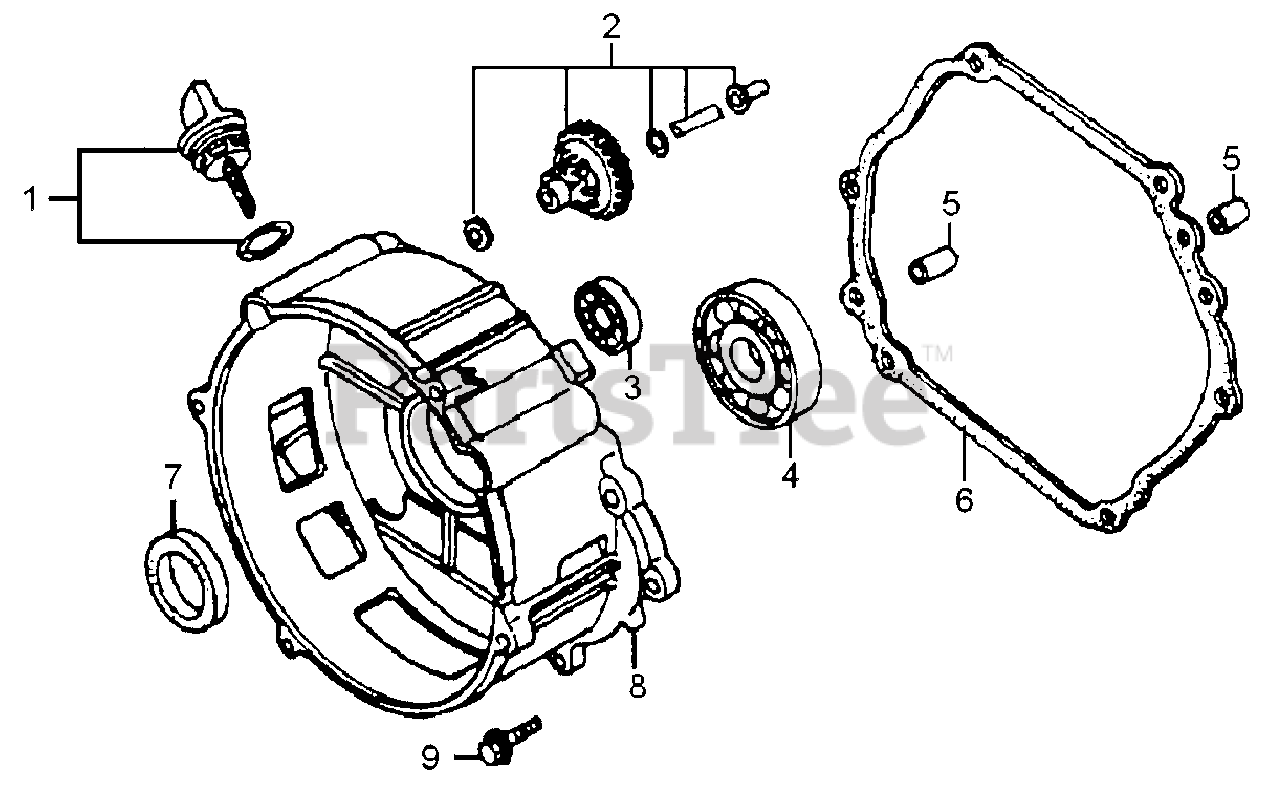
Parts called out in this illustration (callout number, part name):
1	CAP COMP., OIL FILLER
2	GOVERNOR ASSY.
3	BEARING, RADIAL BALL 6202
4	BEARING, RADIAL BALL 6207
5	PIN, DOWEL 8×12
6	GASKET, CASE COVER
7	OIL SEAL 35×52×7
8	CRANKCASE COVER
9	BOLT, FLANGE M8×40
